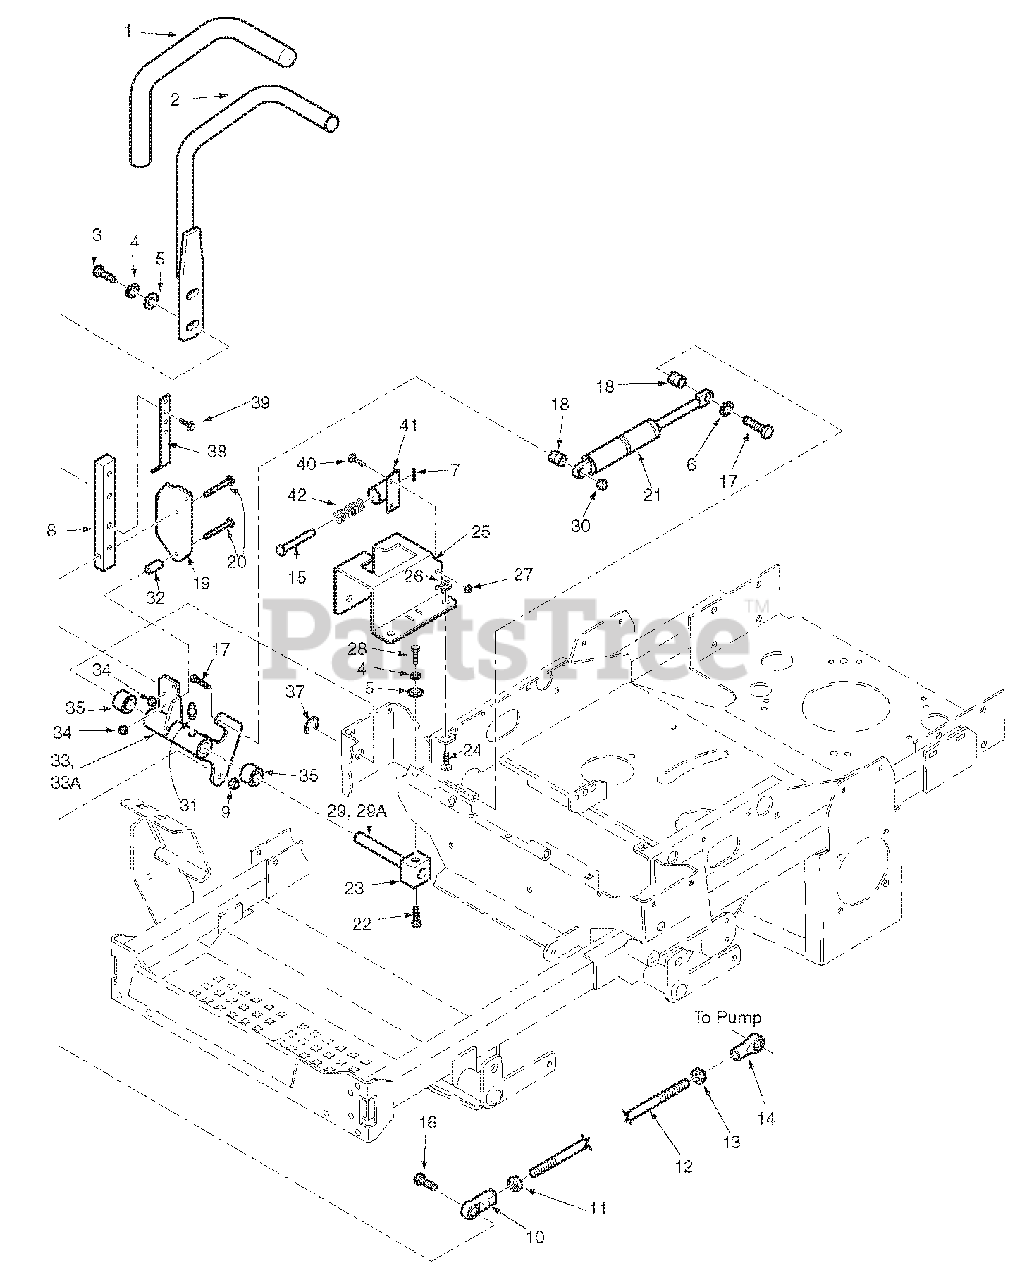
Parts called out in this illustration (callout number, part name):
1	Grip, Control Lever
2	Handle Bar
3	Bolt, Hex Head 3/8-16 x 1-1/4"
4	Lockwasher, 3/8"
5	Flatwasher, 3/8-.391 x .938 x .105"
6	Flatwasher, 5/16-.375 x .875 x .083"
7	Roll Pin, Spring 5/32 x 3/4"
8	Bar, Control Lever
9	Nut, Elastic Stop 3/8-16
10	Rod End, 3/8-24 RH Female
11	Nut, 3/8-24 RH Thread
12	Rod, Pump Control Linkage
13	Nut, 3/8-24 UNF-2B LH Thread
14	Rod End, 3/8-24 LH Thread
15	Pin Retainer
16	Bolt, Hex Head 3/8-16 x 1-1/2"
17	Bolt, Hex Head 5/16-18 x 1-3/4"
18	Spacer, Pump Dampener
19	Plate, Control Lever
20	Bolt, Hex Head 5/16-18 x 2"
21	Gas Damper
22	Bolt, Hex Head 3/8-16 x 1"
23	Block, Clamping
24	Bolt, Carriage, 5/16-18 x 3/4"
25	Control Plate - LH
25	Control Plate - RH
26	Nut, Serr., Flange, 5/16-18
27	Nut, Elastic Stop 1/4-20
28	Bolt, Hex Head 3/8-16 x 3/4"
29	Shaft, Steering Control
30	Nut, Elastic Stop 5/16-18
31	Grease Fitting, 1/4-28 Self Tap
32	Spacer, Control
33	Control Lever Assy RH
33	Control Lever Assy LH
34	Nut, Elastic Stop 5/16-18
35	Bushing
36	Flatwasher, 1-1/4 x 49/64 x 16 Ga.
37	Retaining Ring, 3/4" Ext.
38	Bracket, Switch Actuator
39	Bolt, Hex Serr. Flange 5/16-18 x 3/4"
40	Bolt, Carr. 1/4-20 x 3/4"
41	Bracket, Control Return
42	Spring
43	Pin Retainer
